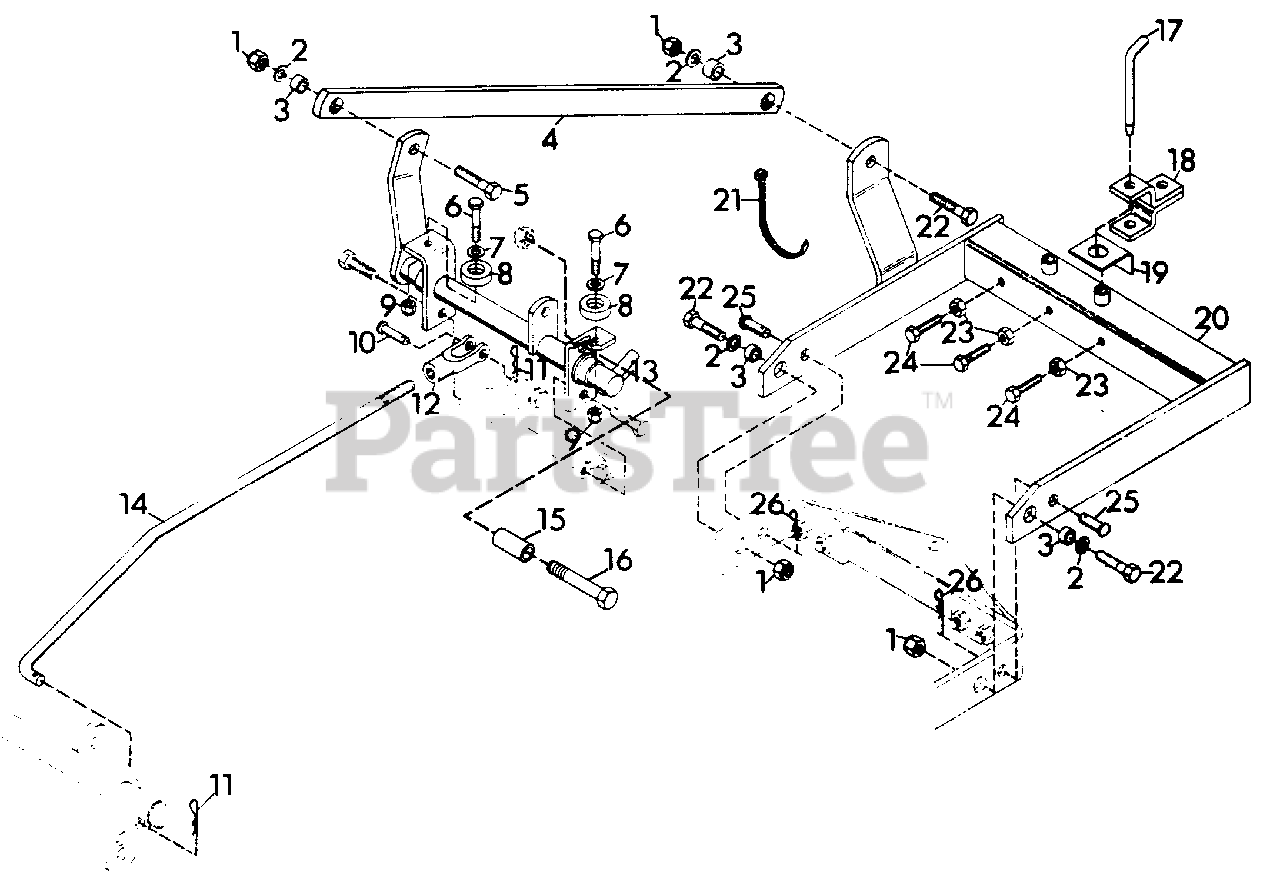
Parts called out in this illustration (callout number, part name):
1	NUT, LOCK 1/2-13
2	WASHER, FLAT .531X1.062X.095
3	BUSHING, PIVOT CASTING
4	STRAP, REAR HITCH
5	BOLT, HEX 1/2-13X2.00
6	BOLT, HEX 1/4-20X1.25
7	WASHER, FLAT .312X.734X.065
8	BUMPER, SEAT
9	NUT, LOCK 1/4-20
10	PIN, CLEVIS .500X1.213
11	PIN, COTTER HAIR
12	YOKE, ADJUSTABLE
13	WELDMENT, LIFTABLE HITCH
14	ROD, LIFT
15	BUSHING, .505X.74X1.438
16	BOLT, HEX 1/2-13X2.75
16	BOLT, HEX 1/2-13X3.50
17	PIN, HITCH
18	HITCH, REAR WELDMENT
19	PAD
20	WELDMENT, REAR HITCH
21	TIE, CABLE
22	BOLT, HEX 1/2-13X1.75
23	NUT, JAM 3/8-16 HEX HEAVY
24	BOLT, HEX SPECIAL 3/8-16X3.00
25	PIN, CLEVIS 5/8X1.125
26	PIN, HAIR
